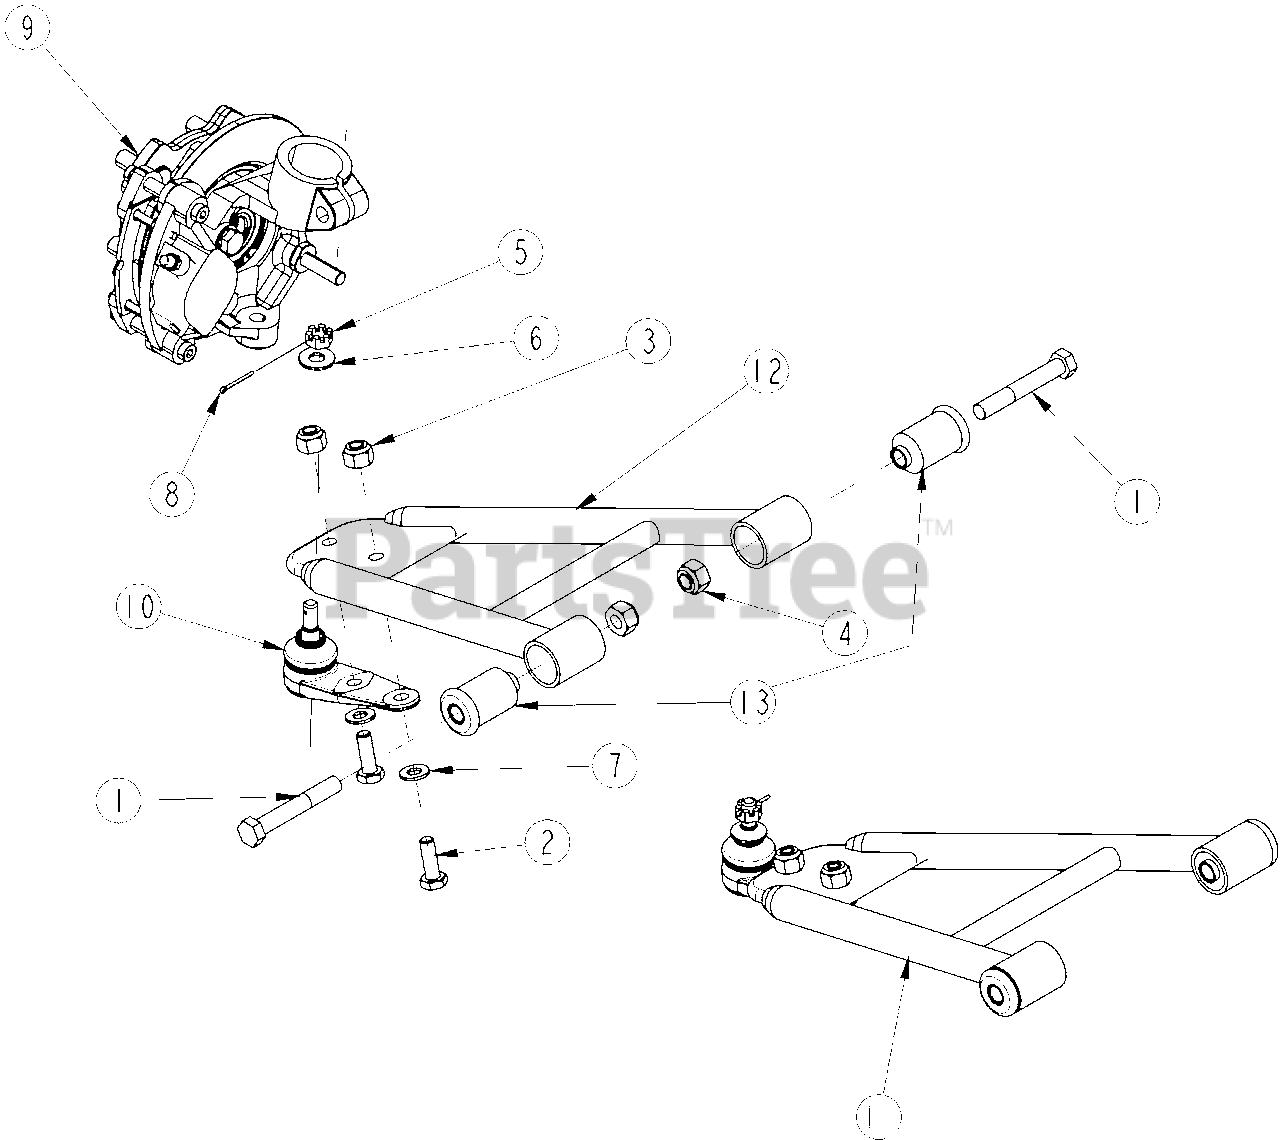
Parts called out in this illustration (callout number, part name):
1	HHCS M12X1.75X80 GR8.8 PLT
2	HHCS M10X1.5X30 GR8.8
3	NUT HEX NYLOCK M10X1.5 PLT
4	NUT HEX NYLOCK M12X1.75 PLT
5	NUT HEX SLOTTED M10X1.25 PLT
6	WASHER FLAT 3/8 USS PLT
7	WASHER, FLAT STEEL .438 x 1.00 x .083
8	PIN COTTER 3/32 X 1 LONG
9	RH DISC BRAKE ASM 172mm W/JNT
9	LH DISC BRAKE ASM 172mm W/JNT
10	BALL JOINT BOLT ON SIR Includes No. 2, 3, 5, 6, 7, 8, 10, 11, 12 & 13
11	A-ARM, RIGHT ASSEMBLY Includes No. 2, 3, 5, 6, 7, 8, 10, 11, 12 & 13
11	A-ARM, LEFT ASSEMBLY
12	A-ARM, NEW BUSHING
13	BUSHING, A-ARM
